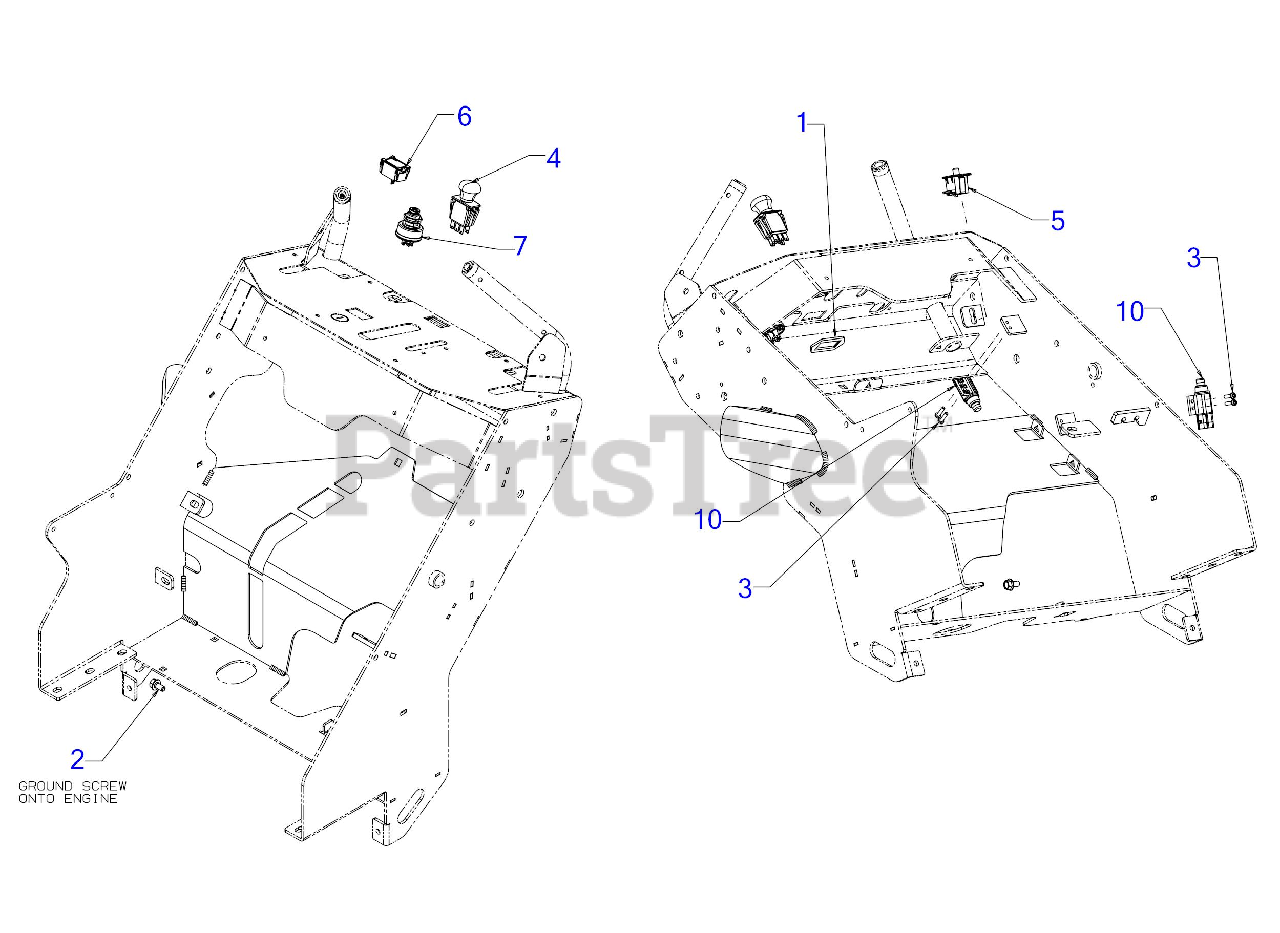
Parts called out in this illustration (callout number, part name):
1	BRACKET-PTO SWITCH
2	SCREW M8 x 1.25 x 16MM GR8.8
3	SCREW (10-24X.75:PH:TAP:T25:GR5)
4	PTO SWITCH (BLACK KNOB) TEXT SYM
5	SEAT SWITCH
7	KEY SWITCH (3 POSITION) (Add 925-06908)
10	SEALED PLUNGER SWITCH
